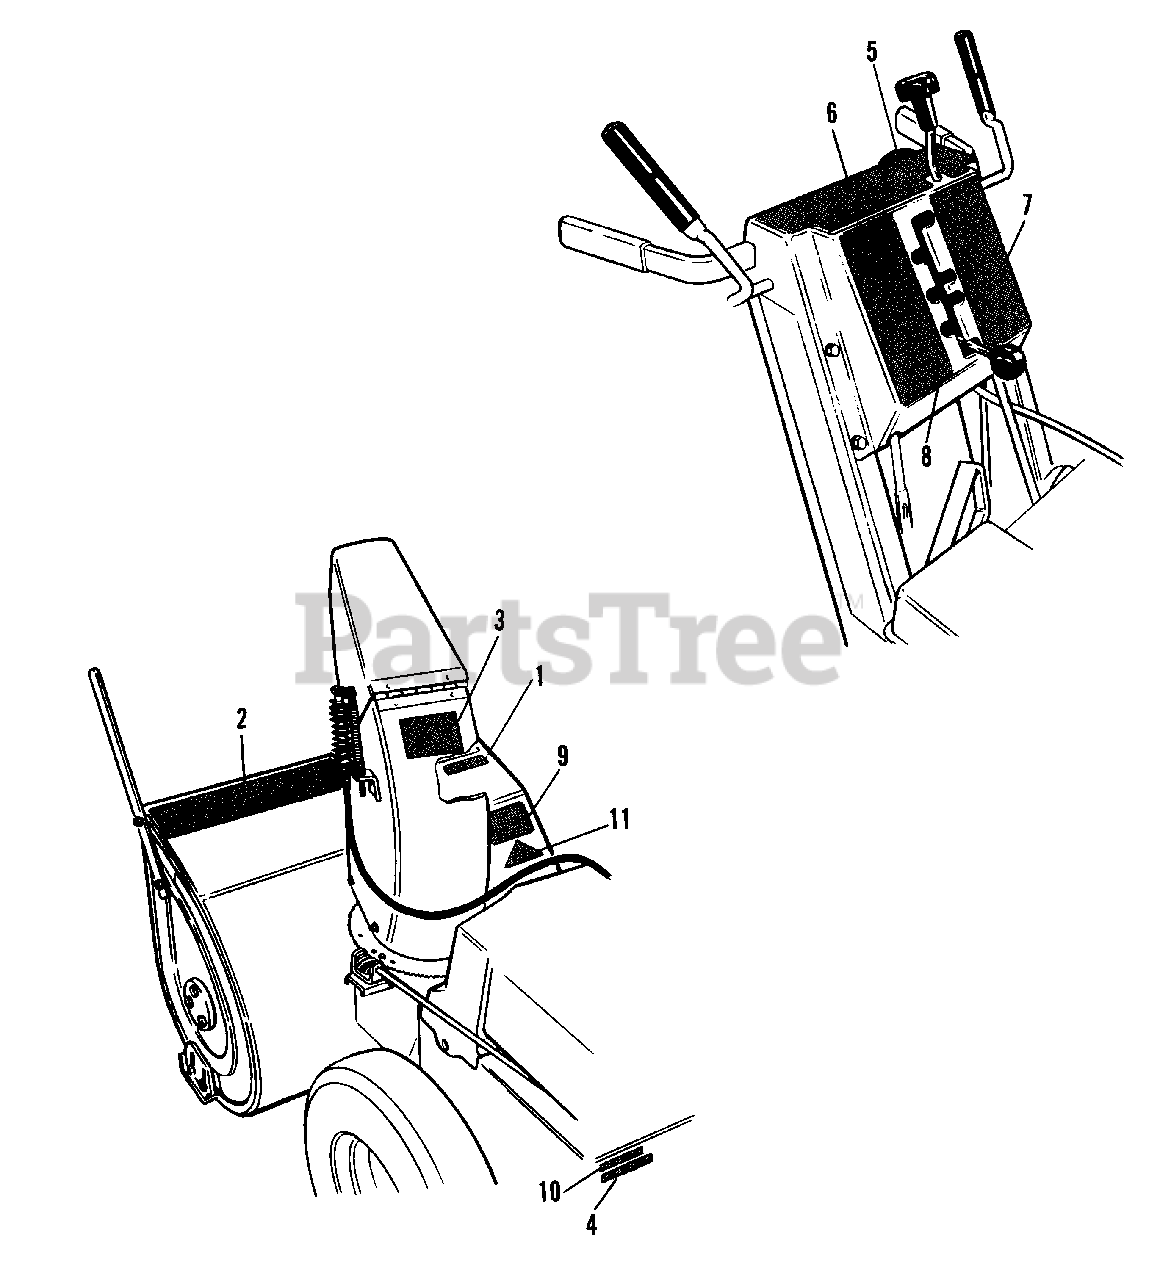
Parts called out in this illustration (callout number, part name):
1	DECAL, Housing, 560S
1	DECAL, Housing, 870S
1	DECAL, Housing, 1080S
2	DECAL, Auger, Simplicity Logo (560S)
2	DECAL, Auger, Simplicity Logo (870S)
2	DECAL, Auger, Simplicity Logo (1080S)
2	DECAL, Auger, Sno-Away 870
2	DECAL, Auger, Sno-Away 1080
3	DECAL, Danger, Blower
4	DECAL, Touch Up Paint
5	DECAL, Cable Lock (1691774, 1691775, 1691776, 1691779)
6	DECAL, Dash (1691774, 1691775, 1691776, 1691779)
6	DECAL, Dash (1691898,1691899, 1691947, 1691948)
7	DECAL, Shift Pattern, L.H.
8	DECAL, Shift Pattern, R.H.
9	DECAL, Danger, Auger
10	I.D. Tag
11	DECAL, OPEI
